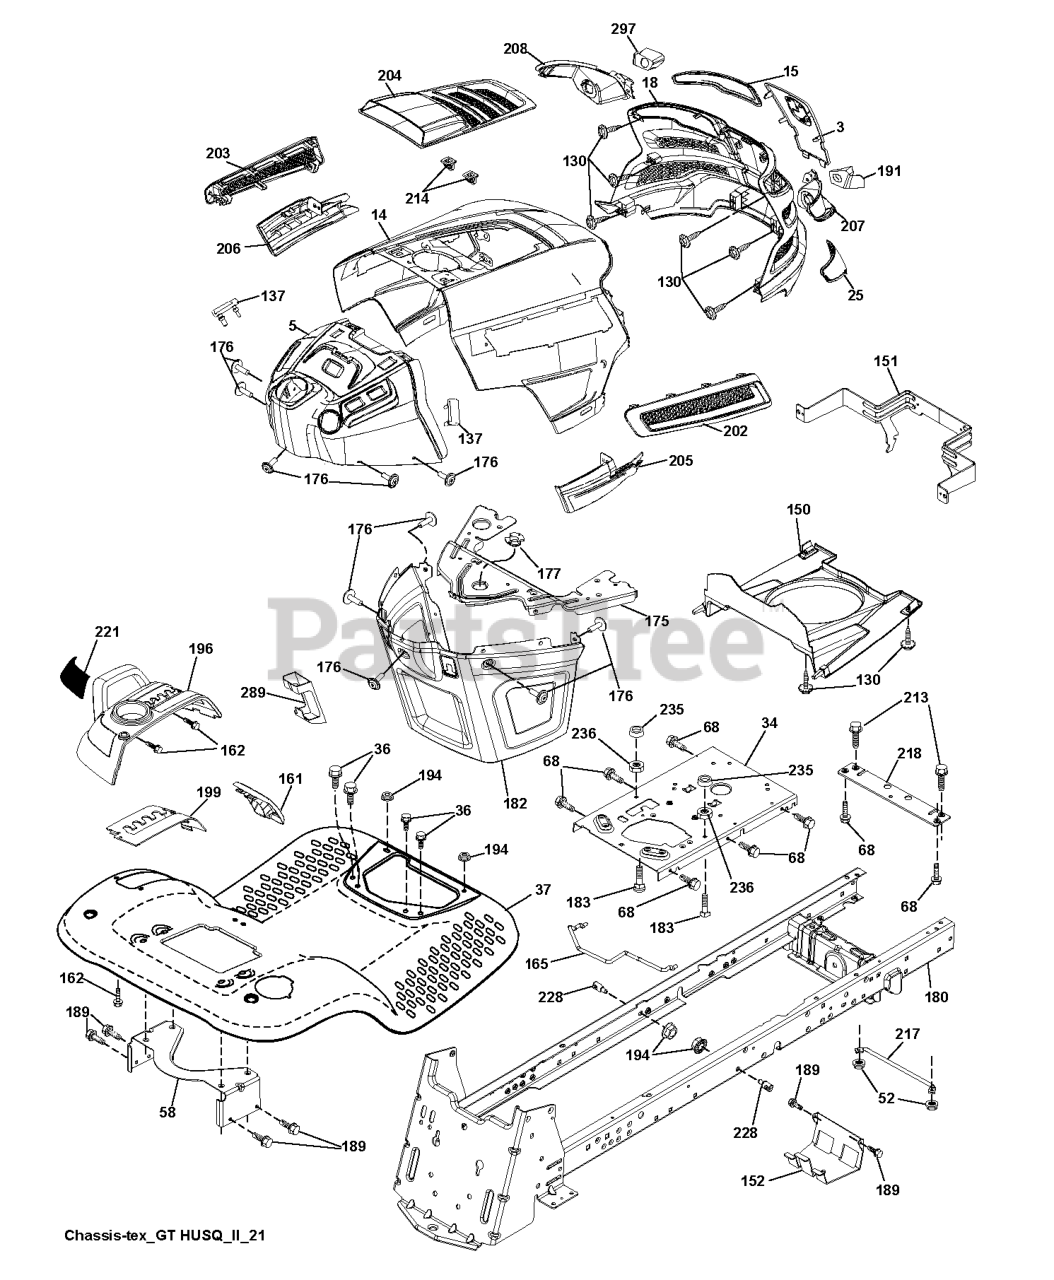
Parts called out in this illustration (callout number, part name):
3	APPLIQUE.SUBASM.GT.HUSQ.II
5	DASH.UPPER.GT2.SM.PTO.M/CH.GRE
14	HOOD.ASM.HUSQVARNA.GT.TEX.ORAN
15	LENS.HEADLIGHT.LH.GTII.2011
18	GRILL.ASM.HUSQ.TG/CRD.W/TRIM
25	LENS.HEADLIGHT.RH.GTII.2011
34	PLATE.ENGINE.WELDED.CHASSIS
36	SCREW 5/16"
37	FENDER.PNT.TX.GT.CH/FW/DL.HUSQ
52	LOCKNUT
58	BRKT.SUPPORT.FNDR/TANK
68	Screw 5/16-18 x 1/2 Hex, Self Tapping 5/16-18 x 1/2
130	SCREW.#10 X 0.750.BOS
137	BUMPER DASH
150	AIR.DUCT.GTV.BLACK
151	BRACKET.PIVOT.HOOD.GT.HUSQ.II
152	SHIELD.BROWNING.W/TEX
161	CONSOLE.WINDOW.FUEL.HUSQ.GT
162	SCREW.HI-LO.CONSOLE
165	SUPPORT.TANK.REAR.W/TEX
175	PLATE.CROSSMEMBER.HUSQ
176	SCREW.#10-24X5/8.RN.QU
177	BUSHING, STEERING
180	CHASSIS.GT.SLOPED.DRAWBAR.
182	DASH.LOWER.COMMON.12V.ADAPTOR
183	BOLT.5/16-18X1-1/4 FULL THD
189	SCREW
191	INSERT.REFLECTIVE.RH.HUSQ.GTII
194	NUT LOCK HEX FLANGE 5/16-18
196	RP CONSOLE.ASM.DECKLFT.W/
199	PLATE.DECK.LIFT.HUSQVARNA.GT
202	VENT.SIDE.RH.GT.HUSQ.II.
203	VENT.SIDE.LH.GT.HUSQ.II.498
204	VENT.TOP.HUSQ.GT2
205	SIDE.TRIM.RH.GT.HUSQ.II
206	SIDE.TRIM.LH.GT.HUSQ.II.GRAY
207	BEZEL LIGHT.RH.GT.II.MYLAR
208	BEZEL LIGHT.LH.GT.II.MYLAR
213	BOLT
214	CLIP.RETAINER.TINNER.
217	ROD.PIVOT.HOOD
218	X-PIECE.HOOD.STOP.NON/
221	REFLECTOR.LH.TEX GT HU
228	STUD.FASTNER.W/ANTI-ROTATE
235	SPACER FENDER
236	NUT.CENTERLOCK.5/16-
289	PLUG.N/CRUISE.COMMON.YT/GT.BLK
297	INSERT.REFLECTIVE.LH.HUSQ.GTII
